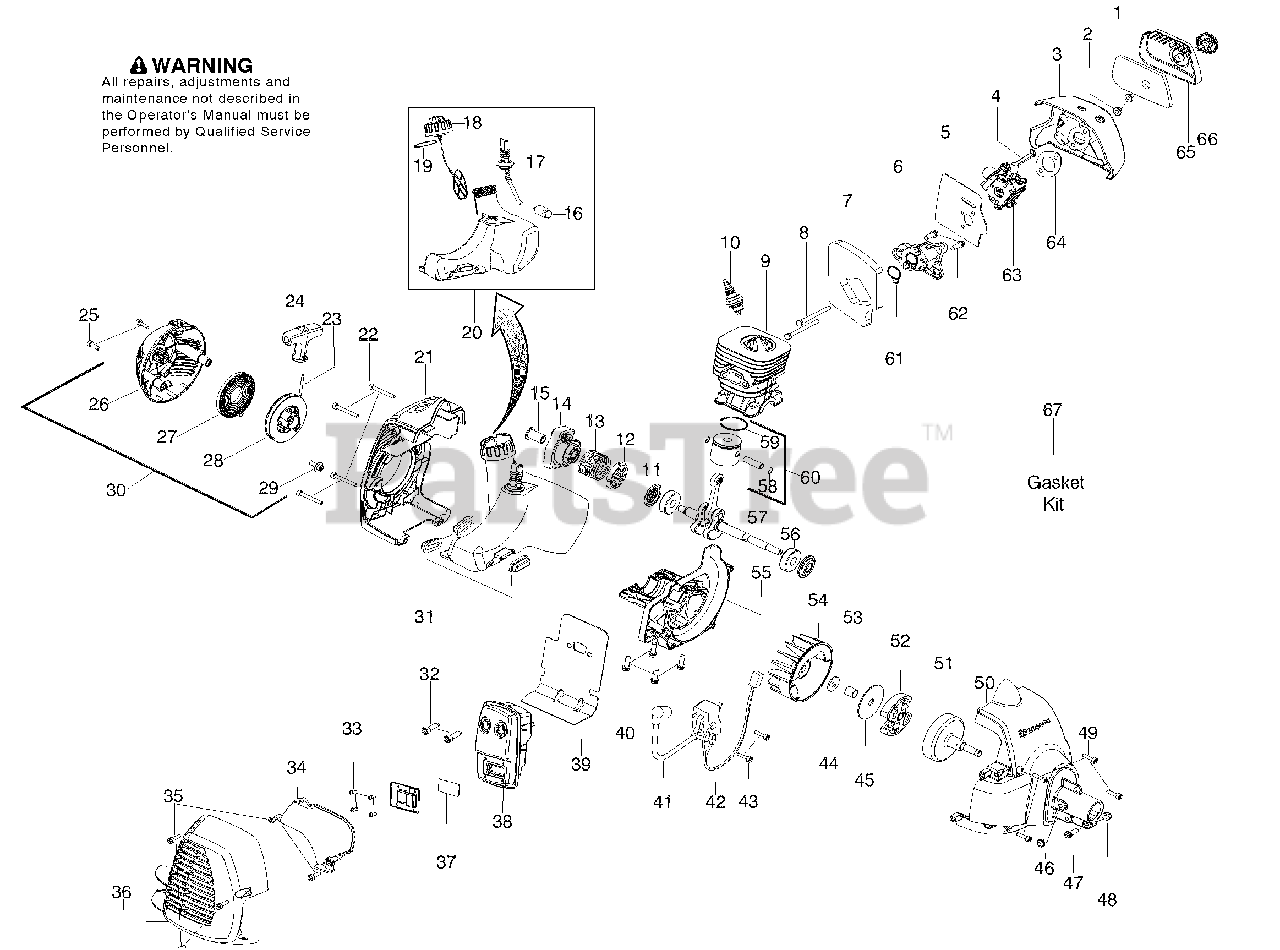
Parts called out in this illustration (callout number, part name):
2	Nut-Carb. Screw
3	Air Box
4	Lever-Choke
5	Kit-Carb. Gasket
6	Adaptor-Carb.
7	Kit-Gasket
9	Cylinder
10	Plug-Spark
11	Kit-Crankshaft seal
12	Washer-Starter
13	Spring-Starter Cup
14	Assy-Starter Cup
15	Coupling-Starter
16	Assy-Fuel Filter
17	Kit-Fuel Line
18	Assy-Cap w/ret
19	O-ring - Fuel Cap
20	Assy-Fuel Tank
21	Shroud-Rear
24	Handle-Starter
26	Starter Hsg. w/eyelet
27	Kit-Starter Spring
28	Kit-Starter Pulley
30	Assy-Starter Hsg.
31	Isolator-Tank
32	Bolt-Muffler
34	Shield-Heat
36	Guard-Muffler
37	Kit-Spark Arrestor
38	Assy-Muffler
39	Gasket-Paper Metal
42	Assy-Leadwire
45	Washer-Clutch
50	Assy-Fan Housing
51	Assy-Clutch Drum
52	Kit-Clutch Assy.
57	Kit-Crankshaft
58	Retainer-Piston Pin
59	Ring-Piston
60	Kit-Piston
61	Kit-Gasket
63	Kit-Carb.
64	Kit-Gasket
65	Cover-Air Box
67	Kit-Gasket
